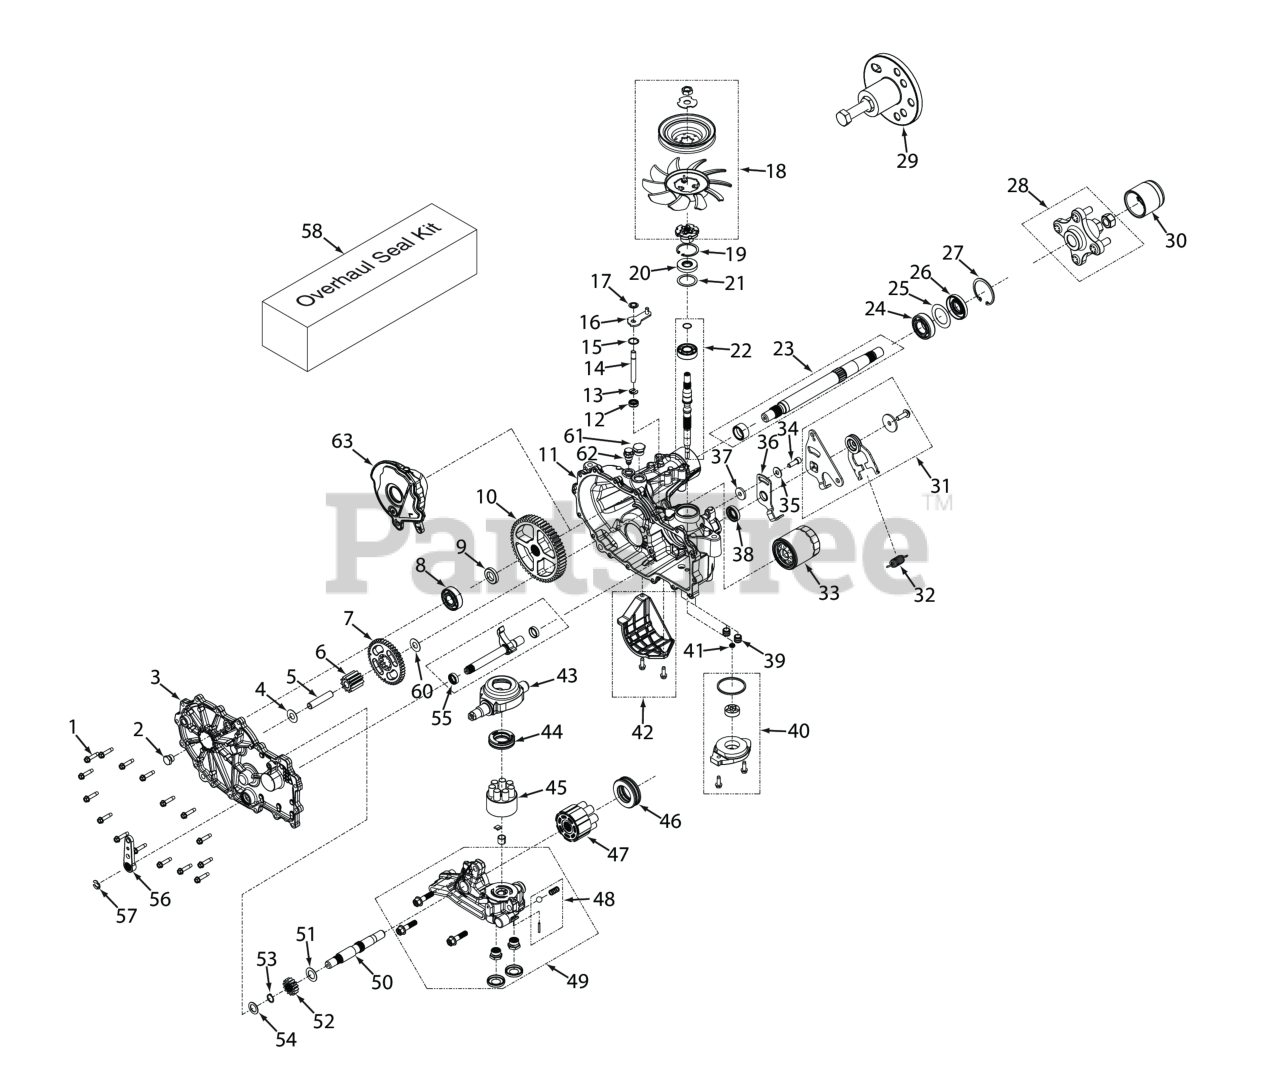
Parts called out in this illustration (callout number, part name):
1	Bolt, Hex Head 1/4-20 x 1-1/8"
2	Plug, External Hex Vent 9/16-18
3	Kit, Side Cover LH
4	Washer, .5 x 1.0 x .03
5	Jackshaft Pin
6	Gear, 11T
7	Gear, 45T
8	Kit, Bearing
9	Spacer, .750 x 1.320 x .257
10	Gear, 54T
11	Kit, Main Housing LH, Charge, Control
12	Seal, Lip, .375 x .75 x .25
13	Ring, .Retaining .375 External
14	Rod, By-Pass
15	R i n g , Retaining .750 Internal
16	Arm, Bypass (LH)
17	Ring, Retainging .375 External
18	Kit, Fan/Pulley
19	R i n g , Retaining 2.06 Internal
20	Seal, Lip 17 x 40 x 7
21	Washer, 1.23 x 1.56 x .04
22	Kit, Input Shaft
23	Kit, Shaft, Axle
24	Bearing, Ball 1.0 x 52 x 15 Open
25	Spacer, 1.355 x 2.035 x .021
26	Seal, Lip TC4 1.0 x 2.06 x .38
27	R i n g , Retaining 2.06 Internal
28	Hub Kit
29	Kit, Hub Puller
30	Cap, Axle
31	Kit, RTN Bi-Directional (Right Side)
32	Spring, Extension, RTN - 44lbs
33	Filter, Oil
34	Bolt, Hex Head Cap Screw 5/16-24 x 1" Patch
35	Washer, 7/16 x 7/8 OD x .06 HT
36	Arm, Neutral (Left Side)
37	Spacer, .32 ID x 1.005 OD x .1495 Thk
38	Seal, Lip 18 x 32 x 7
39	Tube, Charge Triple O-ring
40	Kit, Charge Pump
41	Kit, Gerotor Seal
42	Kit, Filter Guard (LH)
43	Trunnion, Swashplate
44	Ball Thrust Bearing
45	Kit, Cylinder Block
46	Thrust Ball Bearing Assembly
47	Kit, 16cc Cylinder Block Assembly (steam
48	Kit, Charge Relief
49	Kit, Charge Relief
50	Shaft, Motor
51	Washer, .72 x 1.16 x .04
52	Washer, Flat, .71 x 1.16 x .04
53	Ring, Retaining .625
54	Washer, HT .62 ID x 1.0 OD x .05 Thick
55	Kit, Inboard, RH Rot B / LH Rot A (LH)
56	Handle, Brake
57	Ring, Retaining External .375"
58	Kit, Seal (ZT-2800)
60	Washer, .5 x 1.0 x .03
61	Plug, 3/4-16
62	Fitting 9 /16 - 18, Breather
63	Expansion Tank, Internal LH
